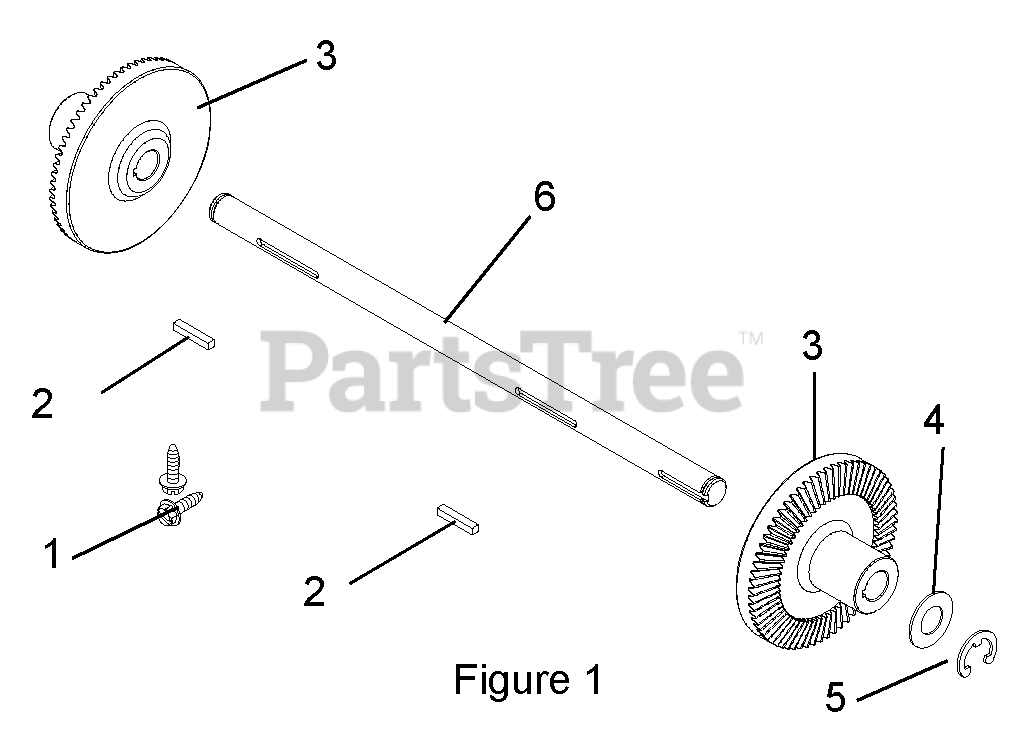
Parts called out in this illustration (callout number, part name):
1	10-24 x 3/8 Tapping Screw
2	1/8 x 1/8 x 1.0 Key
3	Bevel Gear
4	.50 x .75 x .020 Flat Washer
5	Retaining Ring
6	Transmission Output Shaft
